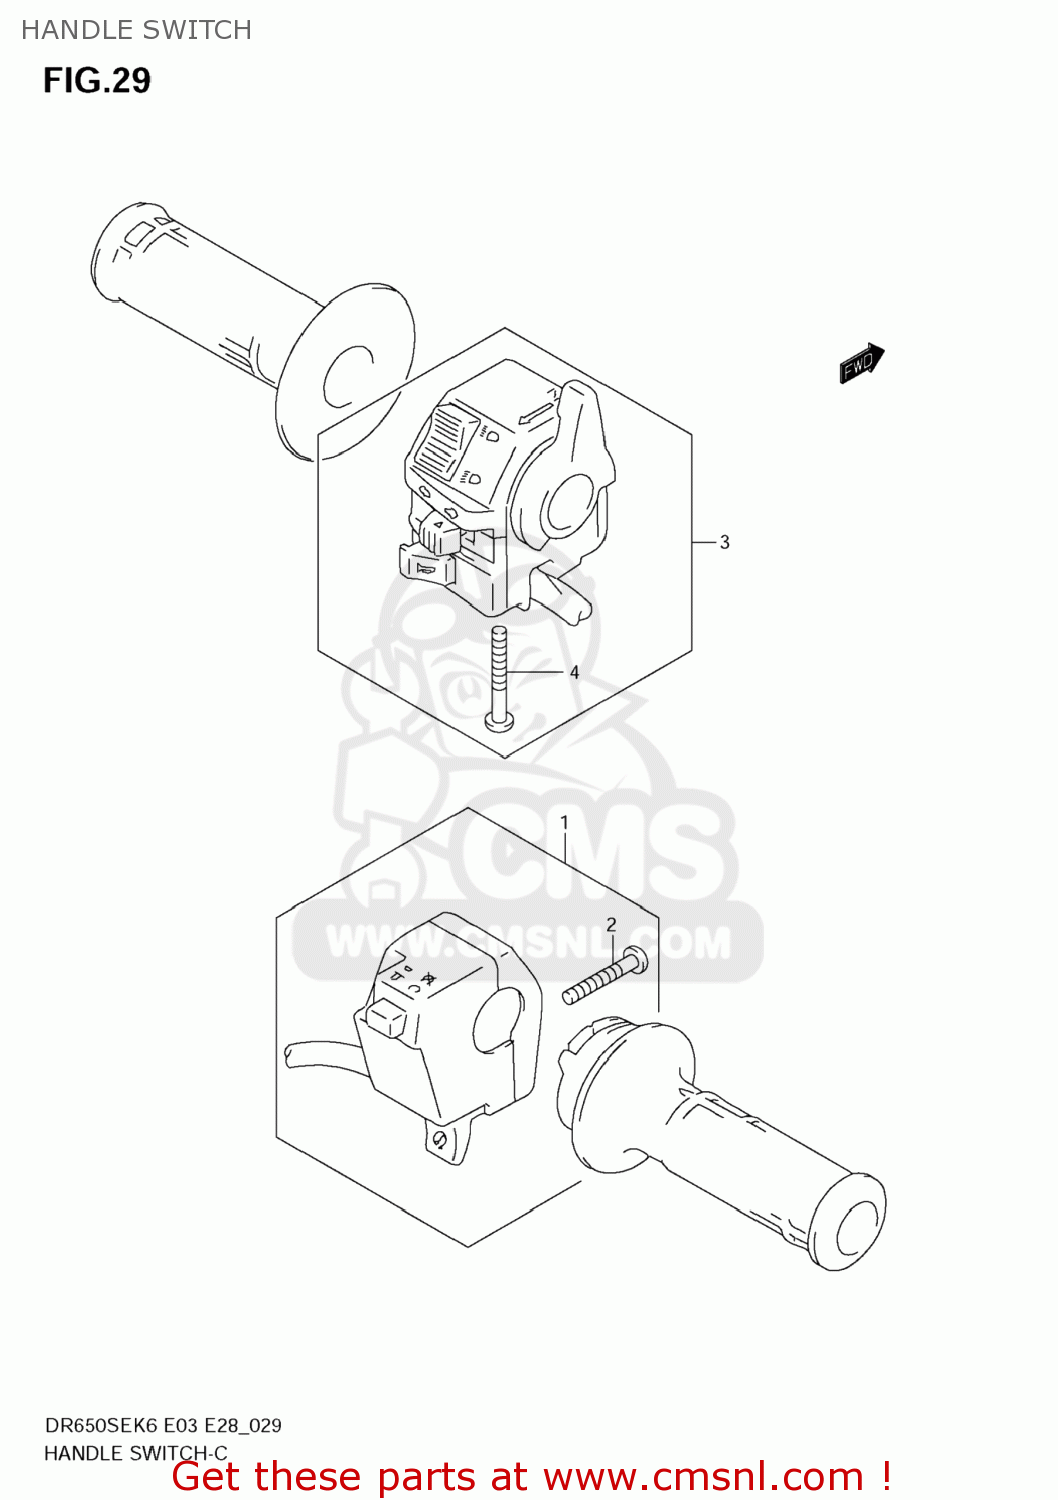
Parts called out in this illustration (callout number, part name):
1	SWITCH ASSY,HANDLE,R
2	SCREW(5X25)
3	SWITCH ASSY,HANDLE,L
4	SCREW, 5X45
